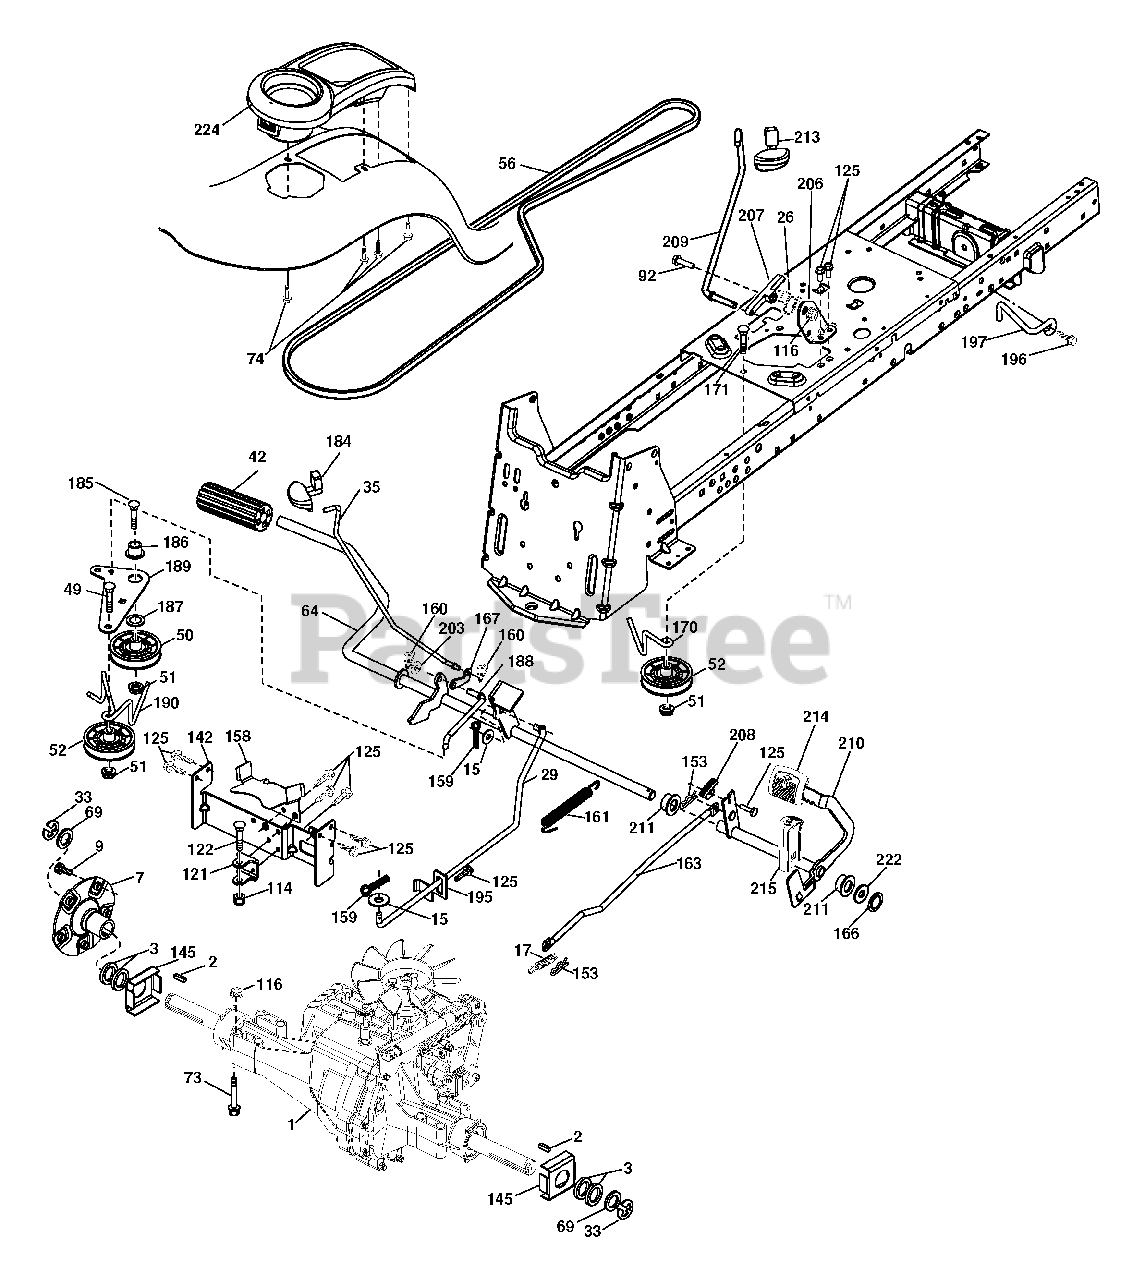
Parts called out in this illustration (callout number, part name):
2	Key 1/4 x 2.5
3	Washer Thrust Axle Hardened
7	Hub Asm. Wheel
9	Bolt Hub Wheel
15	Washer 13/32 x 13/16 x 16 Ga.
17	Spring, Brake
26	Spring Return Cruise
29	Rod, Brake
33	Ring E
35	Rod, Brake, Park
42	Cover, Foot Pedal
49	Bolt
50	Pulley Idler Flat
51	Lock Nut 3/8-16
52	Idler V-Groove 910" Offset
56	V-Belt, Drive
64	Shaft Asm. Pedal Brake Control
69	Washer 1-1/32 x 1-5/8 x 16 Ga.
73	Bolt Hex 5/16-18 x 3 Gr. 5
74	Screw 1/4 x 1/2
92	Bolt 5/16-18 x 1/2
114	Nut Lock Hex W/Ins. 5/16-18 unc
116	Nut Lock Hex Flange 5/16-18
121	Bracket Strap Torque
122	Bolt 5/16-18 x 2.50
125	Screw 5/16-18 x 3/4
142	Strap Torque
145	Washer Axle Flange
153	Retainer Spring
158	Keeper Belt T/A
159	Pin Cotter 1/8 x 3/4
160	Retainer Clip
161	Spring, Return, Clutch
163	Rod Pedal Control
166	Nut Push .625
167	Latch Brake Parking
170	Keeper Belt Centerspan
171	Bolt
184	Handle Parking Brake
185	Bolt Rdhd Sqnk 3/8-16 x 2-1/2
186	Spacer Retainer
187	Washer
188	Link Clutch Ground Drive
189	Bellcrank Ground Drive
190	Keeper Bellcrank Ground Drive
195	Retainer Rod Brake
196	Screw 3/8-16 x 1
197	Bracket Clutch Anti-Rotation
203	Washer 11/32 x 11/16 x 16 Ga.
206	Bracket Mount Latch Cruise
207	Latch Control Cruise
208	Gear Sector Control Cruise
209	Rod Control Cruise
210	Rocker Asm. Pedal Control
211	Bearing Nylon
213	Knob Control Cruise
214	Pedal Forward
215	Pedal Reverse
222	Washer 21/32 x 1-1/4 x 10 Ga.
224	Cover Terminal
